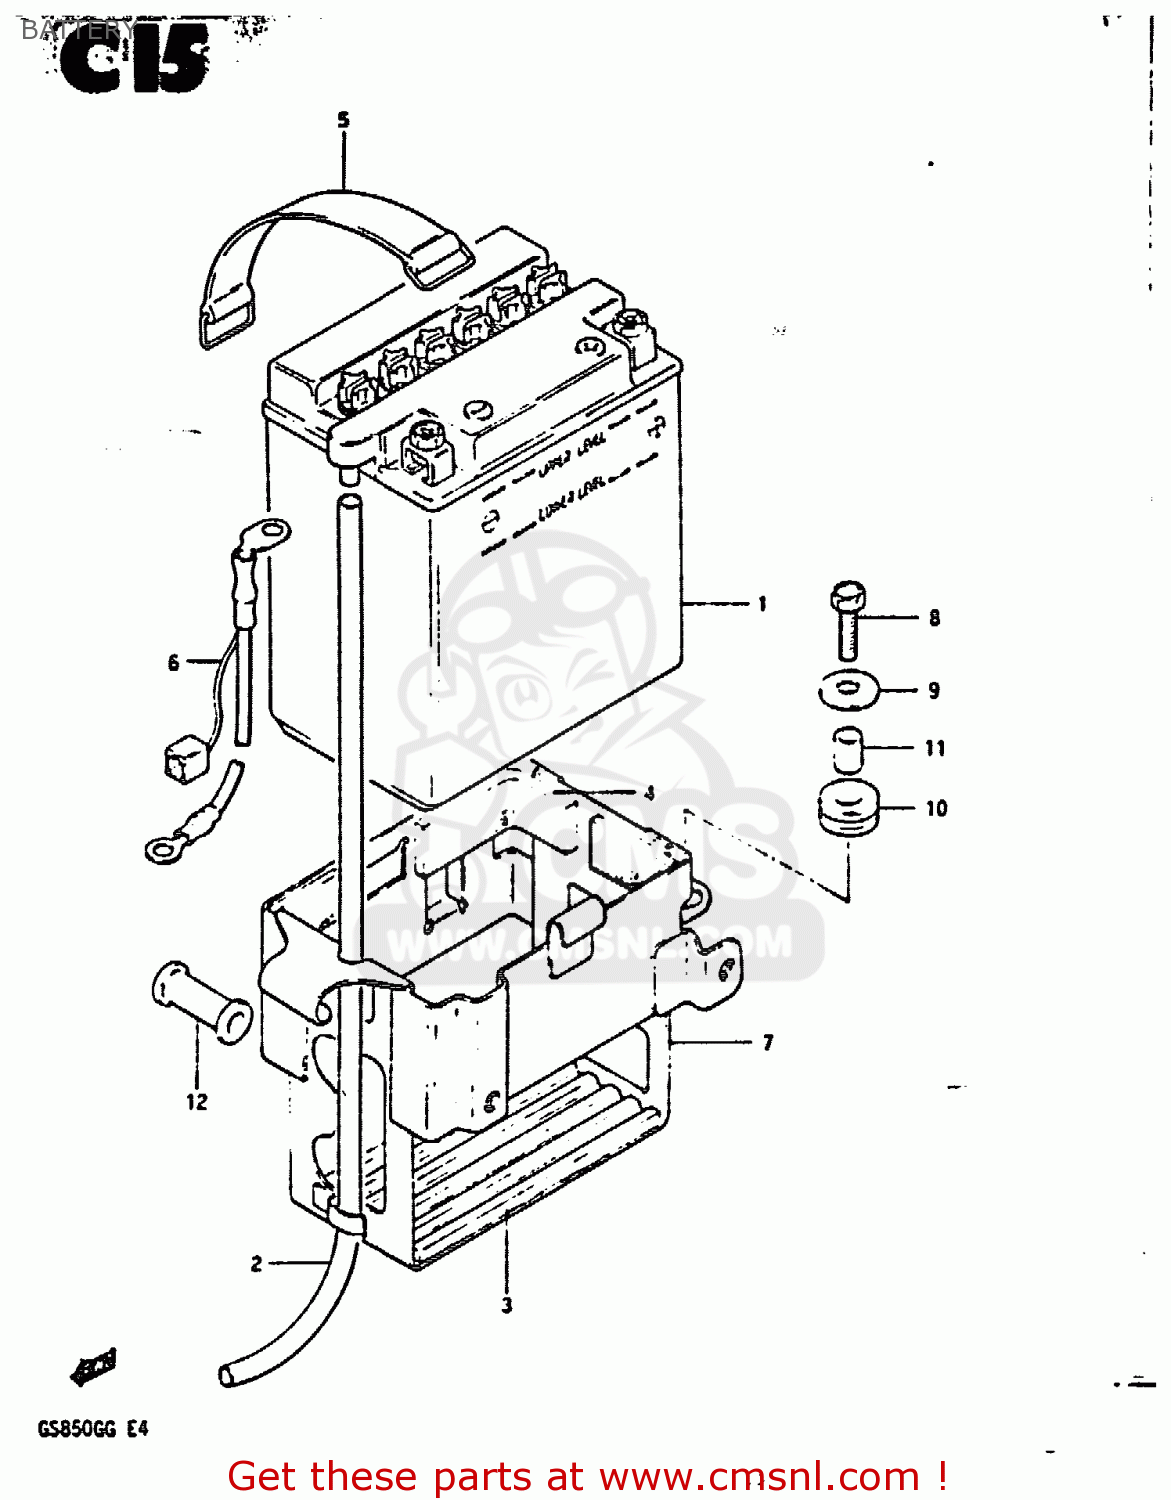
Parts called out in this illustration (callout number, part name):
1	BATTERY ASSY (12V)
2	HOSE,BATTERY EXHAUST
3	PROTECTOR,BATTERY
4	PROTECTOR(170X95X3.0)
5	BAND
6	WIRE,BATTERY MINUS LEAD
7	HOLDER,BATTERY
8	BOLT
9	WASHER(6,5X22X1.6)
10	CUSHION
11	SPACER(6.2X8.3X5.7)
12	CUSHION
